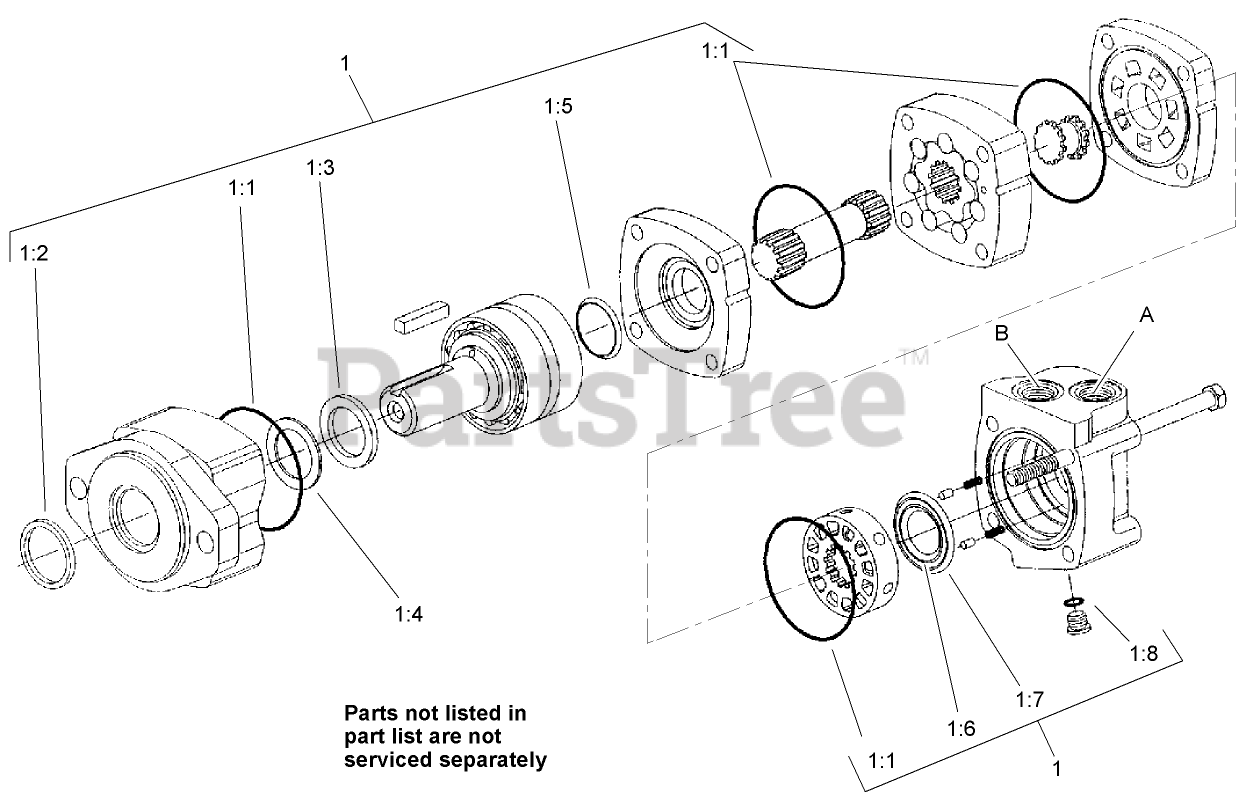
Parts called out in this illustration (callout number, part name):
1	SEAL KIT
1:1	O-Ring
1:2	Seal-Exclusion, Shaft
1:3	Seal-Shaft
1:4	Ring-Back-Up
1:5	Seal-Face, Shaft
1:6	Seal-Face, Inner
1:7	Seal-Face, Outer
1:8	O-Ring
